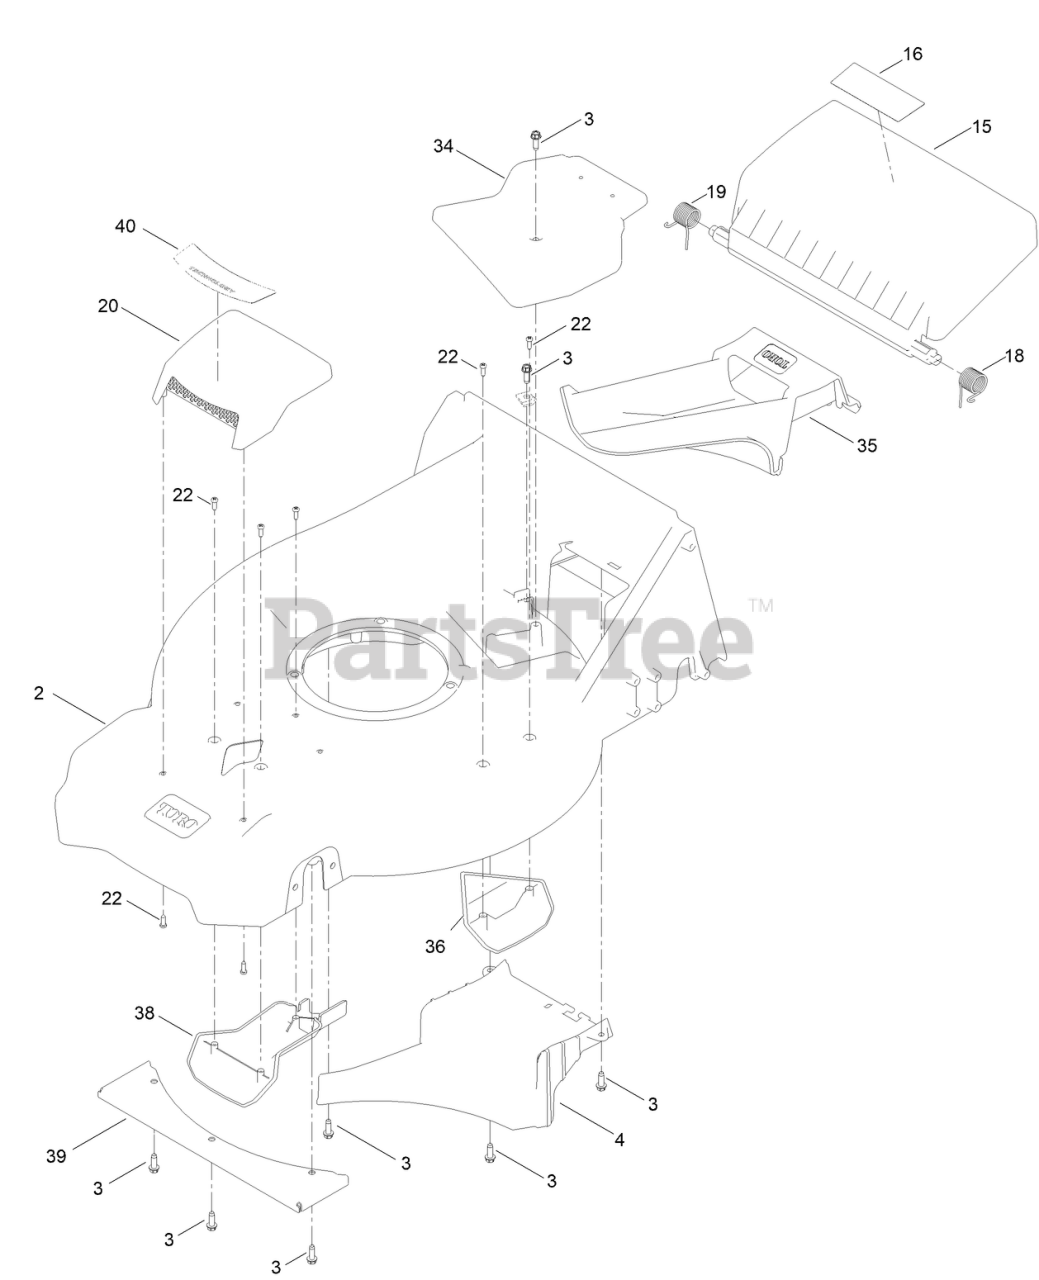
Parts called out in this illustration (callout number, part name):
2	HOUSING ASM
3	SCREW-HWHTF
4	RAMP-DISCHARGE
15	DOOR-REAR
16	DECAL-WARNING
18	SPRING-TORSION, LH
19	SPRING-TORSION, RH
20	ASM-COVER, TOP INTAKE
22	SCREW-PLASTIC, PPH
34	COVER-BELT, TOP
35	PLUG-MULCH
36	KICKER-HOUSING
38	COVER-INTAKE, BOTTOM
39	PLATE-COVER, CE
